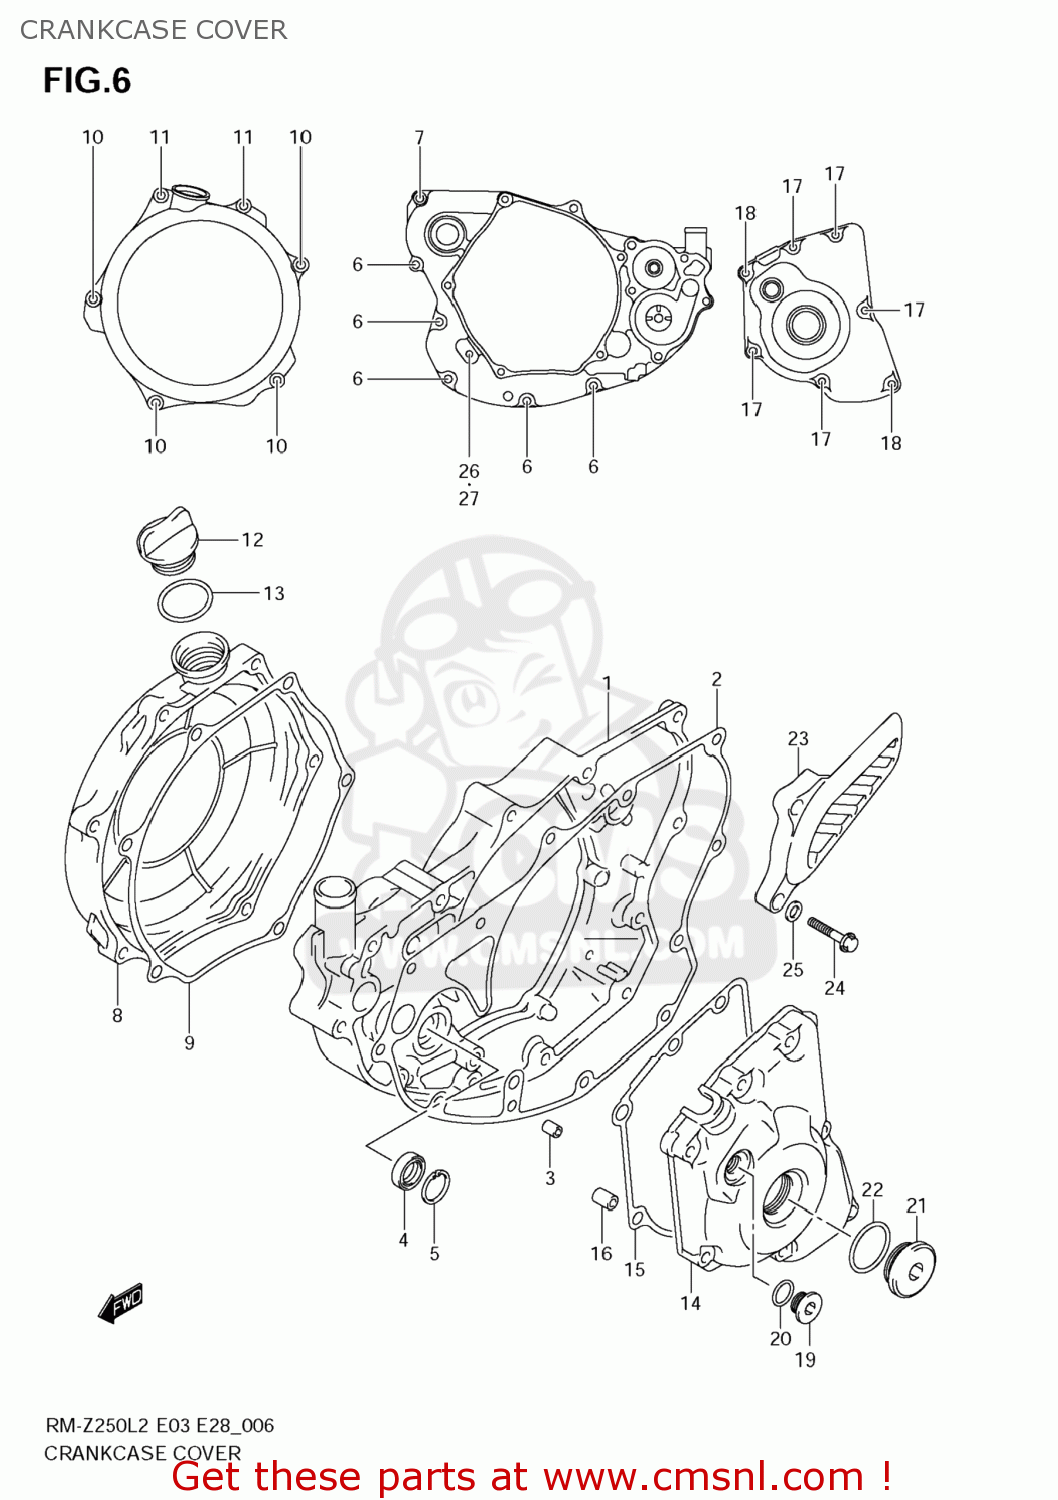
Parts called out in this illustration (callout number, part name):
1	COVER,CLUTCH
2	GASKET,CLUTCH COVER (NAS)
3	PIN
4	SEAL,OIL(12X22X6)
5	CIRCLIP
6	BOLT
7	BOLT
8	COVER,CLUTCH OUTER
9	GASKET,CLUTCH COVER OUTER (NAS)
10	BOLT
11	BOLT
12	PLUG
13	O RING(D:3.1,ID:16.8)
14	COVER,MAGNETO
15	GASKET,MAGNETO COVER (NAS)
16	PIN
17	BOLT
18	BOLT
19	PLUG(12X9)
20	O RING(D:1.9,ID:9.8)
21	PLUG(26X9)
22	O RING(D:3.1,ID:22.7)
23	COVER,ENGINE SPROCKET
24	BOLT
25	WASHER
26	BOLT
27	GASKET(5.8X13X1.2) (NAS)
